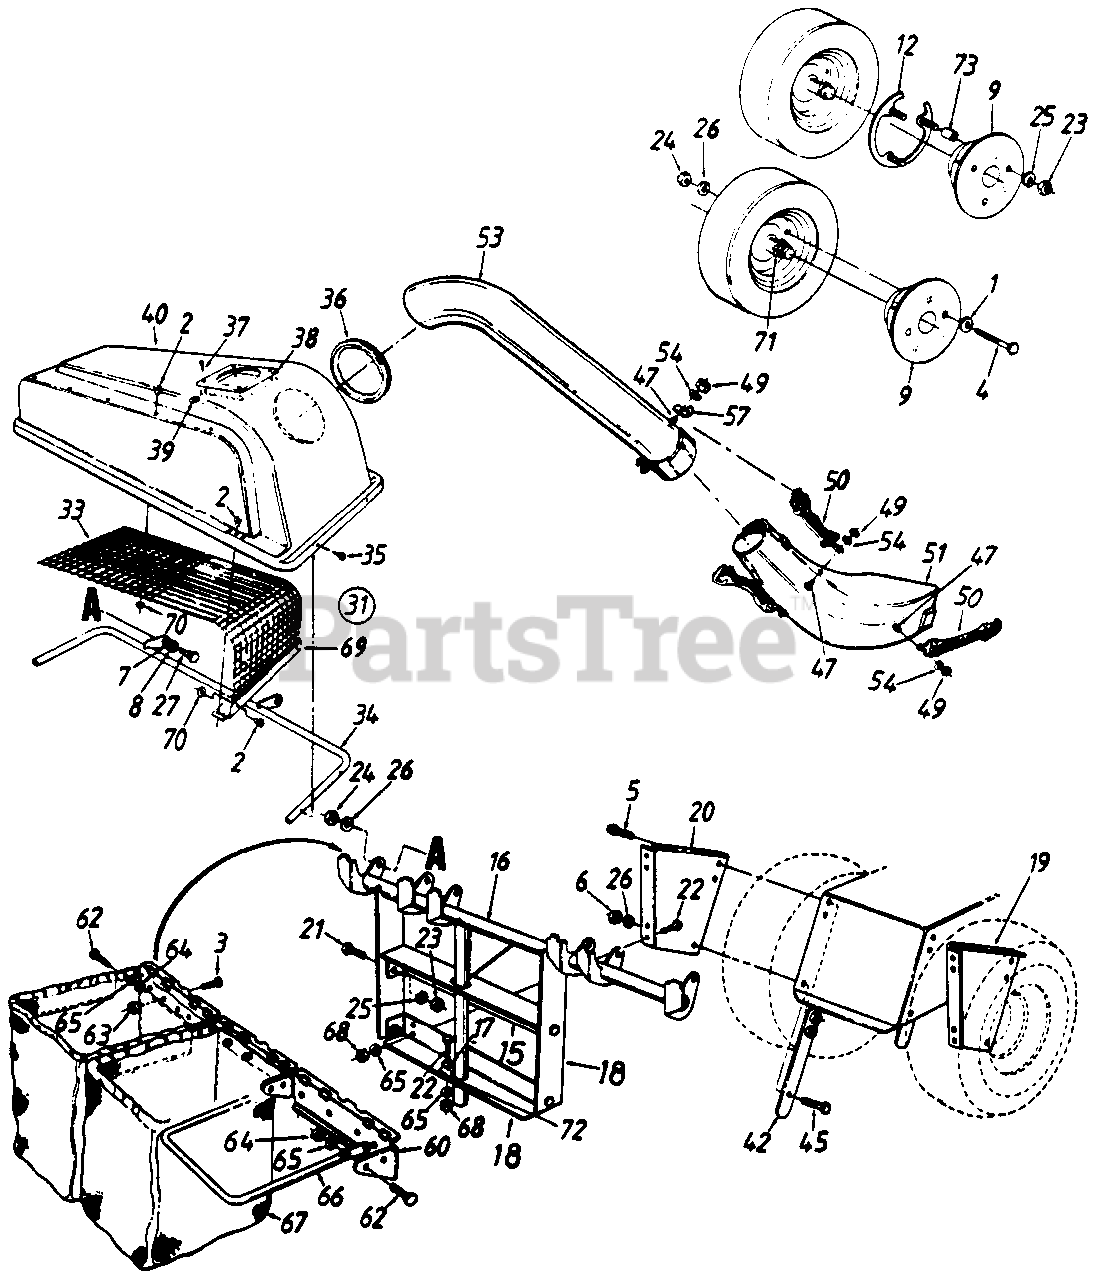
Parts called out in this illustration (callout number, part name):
1	Fl-Wash. .385 I.D.
2	Pop Rivet
3	Truss Mach. Scr. 10-24 x .38 Lg.
4	Hex Bolt 3/8-16 x 4 5 Lg.
5	Hex Wash. Hd. Tap Scr. 5/16-18 x .62"
6	Hex Nut 3/8-24 Thd.
7	Bell-Wash. .515 I.D.
8	Fl-Wash . . 510" 1. D 0 .
9	Wheel Weight
12	Wheel Weight Snap Ring
15	Catcher Support Tube Mtg. Brkt.
18	Catcher Latch and Support Brkt.
22	Hex Bolt 1/ 20 x .62n Lg.- 0 Grade 5
23	Hex Nut SJ16-18 Thd.
24	Hex Nut 3/8-16 Thd.
25	LWash. 5/16" I.D.
26	L Wash. 3/8" l.D.
27	Shld. Bolt 3/8-16 x .SoOn Dia.
31	Grass Catcher Cover Ass'y. Comp.
37	Truss Mach. B-Tap Scr. #0 x.5" Lg.
38	Plastic Plate
39	Speed Nut
40	Grass Catcher Cover
47	Hex Bolt 1/-20 x 50" Lg.
49	Hex Ins. L-Nut 1/4-20 Thd.
50	Retainer Strap Ass'y.
51	Discharge Chute
53	Catcher Elbow Tube
54	L-Wash. 270n l.D. x 57" O.D.
57	Retainer Hook Brkt.
62	Hex Bolt 1/-28 x 75n Lg.
63	Hex Sems Nut #10-24 Thd.
64	Hex Nut 1/4-28 Thd.
65	L-Wash. 1/4 I.D.
66	Catcher Bag Frame
67	Grass Catcher Bag
68	Hex Nut 1/ 20 Thd.
71	Foam Strip 1-1/8" x 1 1/2" x 318"
